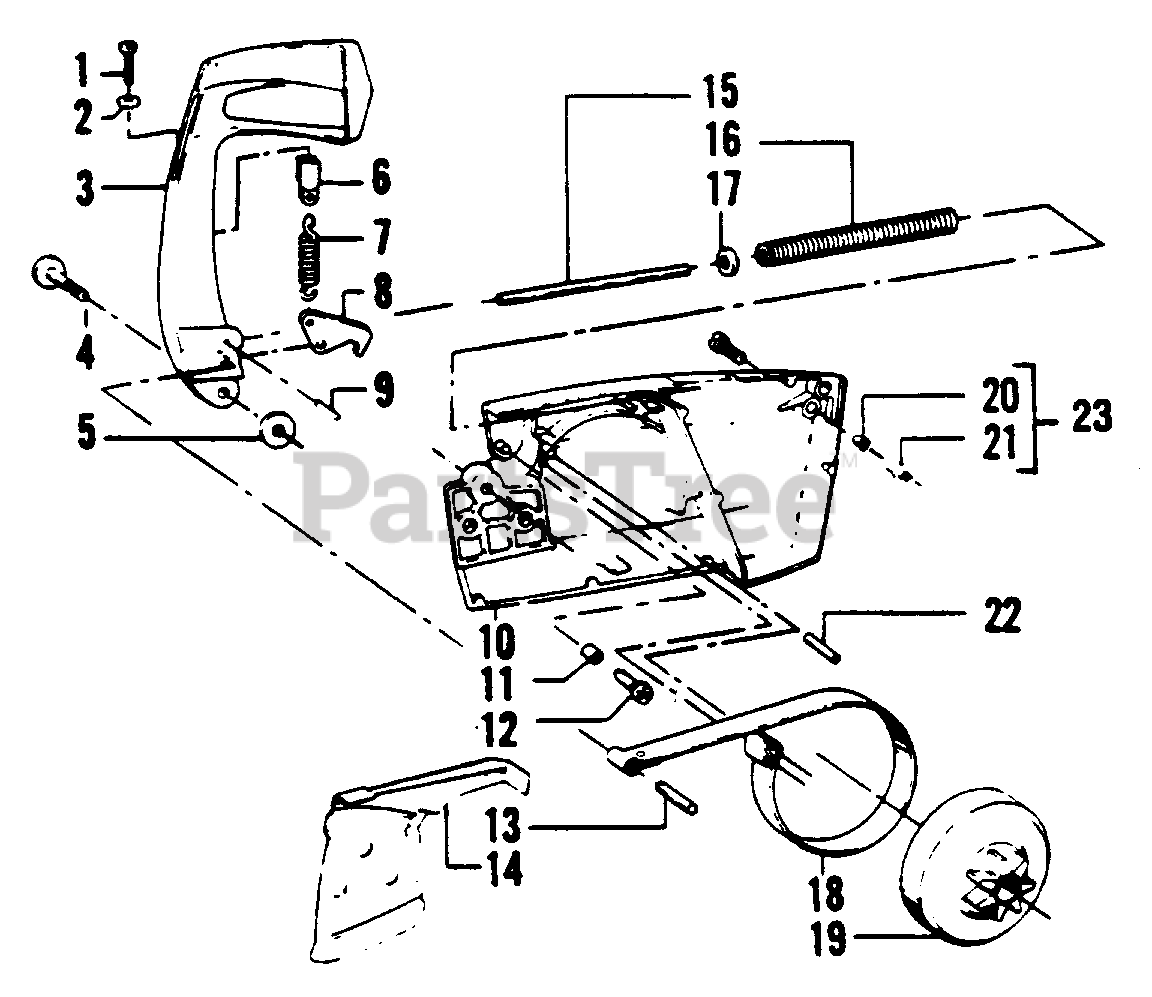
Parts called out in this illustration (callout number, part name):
1	Screw - Slotted Fil. - 10 - 24 x 7/8
2	Washer - Plain Type "B"
3	Actuating Lever
4	Screw Arm Pivot
5	Washer - Pivot Screw
6	Anchor - Extension Spring
7	Spring - Extension
8	Hook - Detent
9	Pin - Support Rod
10	Bar Clamp
11	Roller Latch
12	Boss - Latch Roller
13	Pin - Hook Pivot & Brake Band
14	Guide Bar Plate - Oiler
15	Rod - Spring Support
16	Spring - Compression
17	Washer - Swivel
18	Band - Brake
19	Drum & Sprocket Ass'y
20	Guide Bushing
21	Stud Guide Bar Clamp
22	Dowel Pin
23	Bar Clamp Guide Stud Assy.
